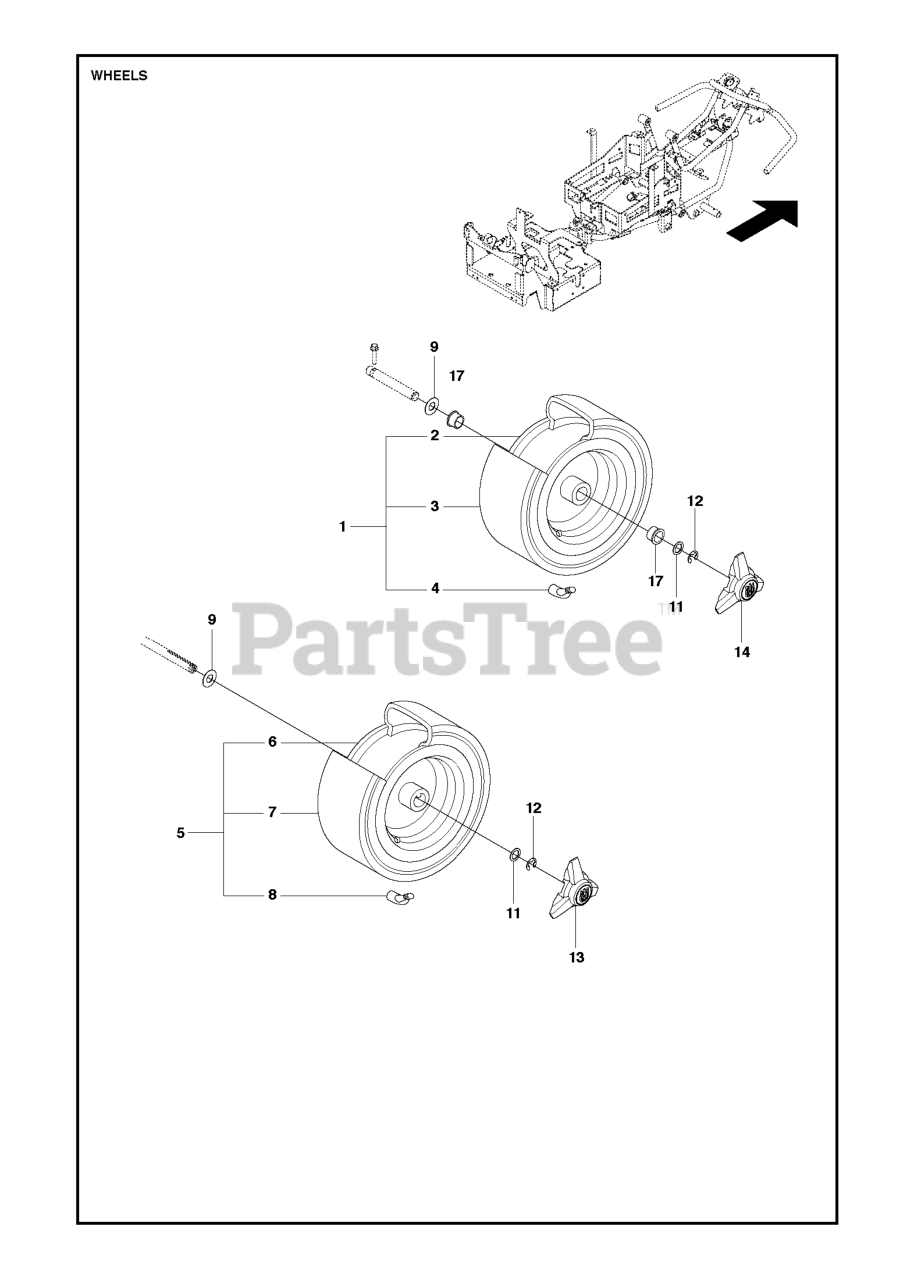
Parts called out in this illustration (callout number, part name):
4	VALVE
8	VALVE
12	RETAINING RING
